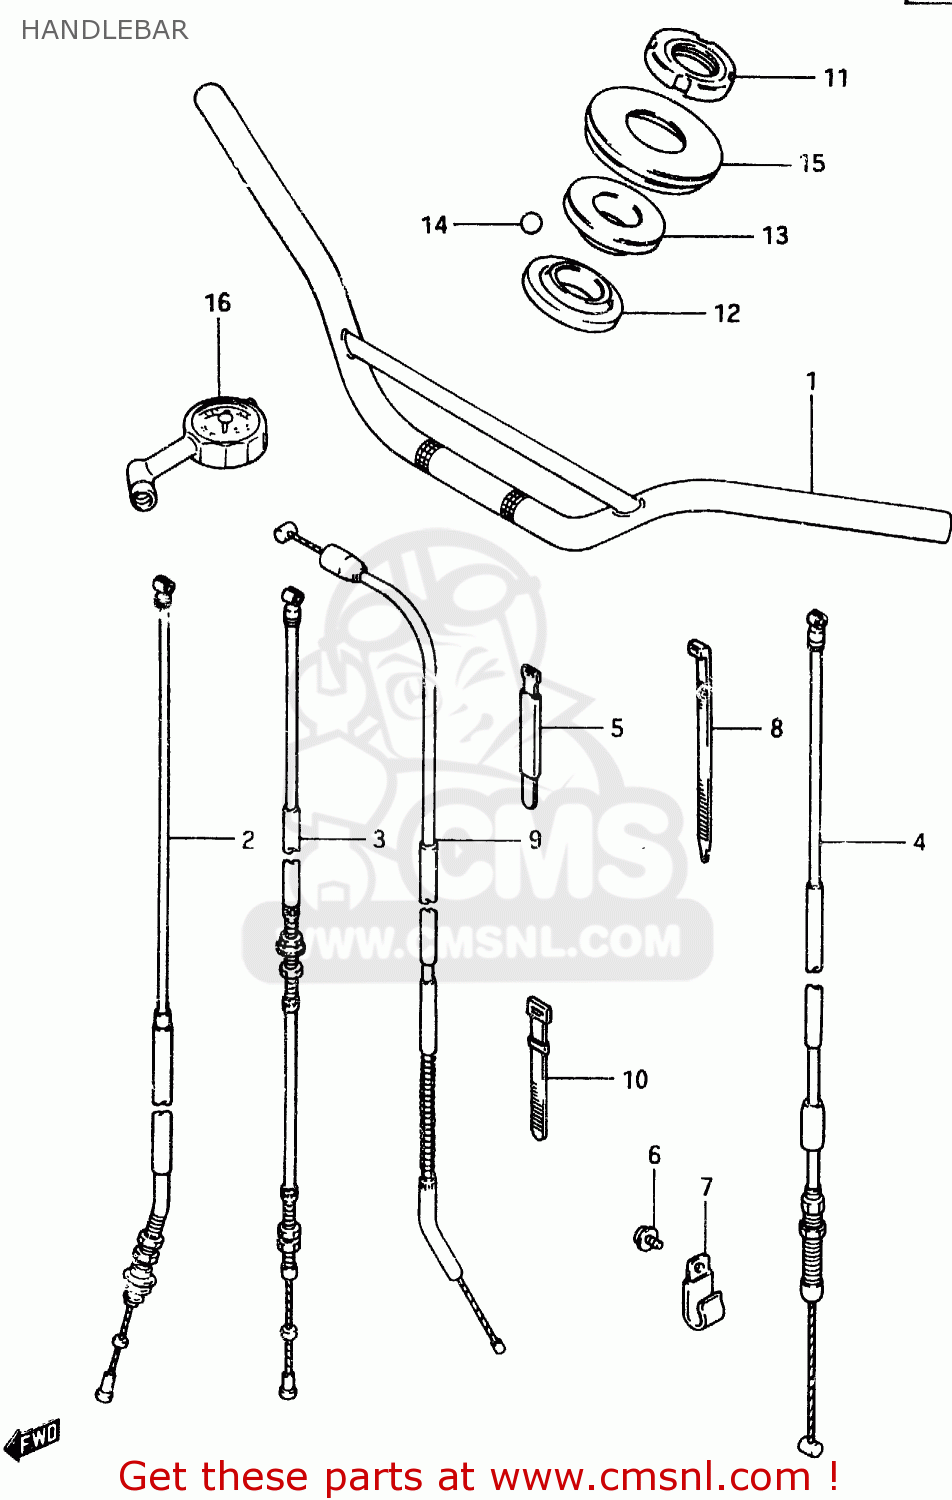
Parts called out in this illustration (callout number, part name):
1	HANDLEBAR
2	CABLE ASSY,FR BRAKE
3	CABLE,FR BRAKE
4	CABLE ASSY,CLUTCH
5	CLAMP
6	SCREW
7	CLAMP
8	CLAMP
9	CABLE ASSEMBLY,THROTTLE
10	CLAMP(L:187)
11	NUT,STEERING STEM
12	RACE,STEERING,INNER,UPPER
13	RACE,STEERING,OUTER,UPPER
14	BALL
15	SEAL,STEERING UPR DUST
16	GAUGE ASSY,AIR PRESSURE
